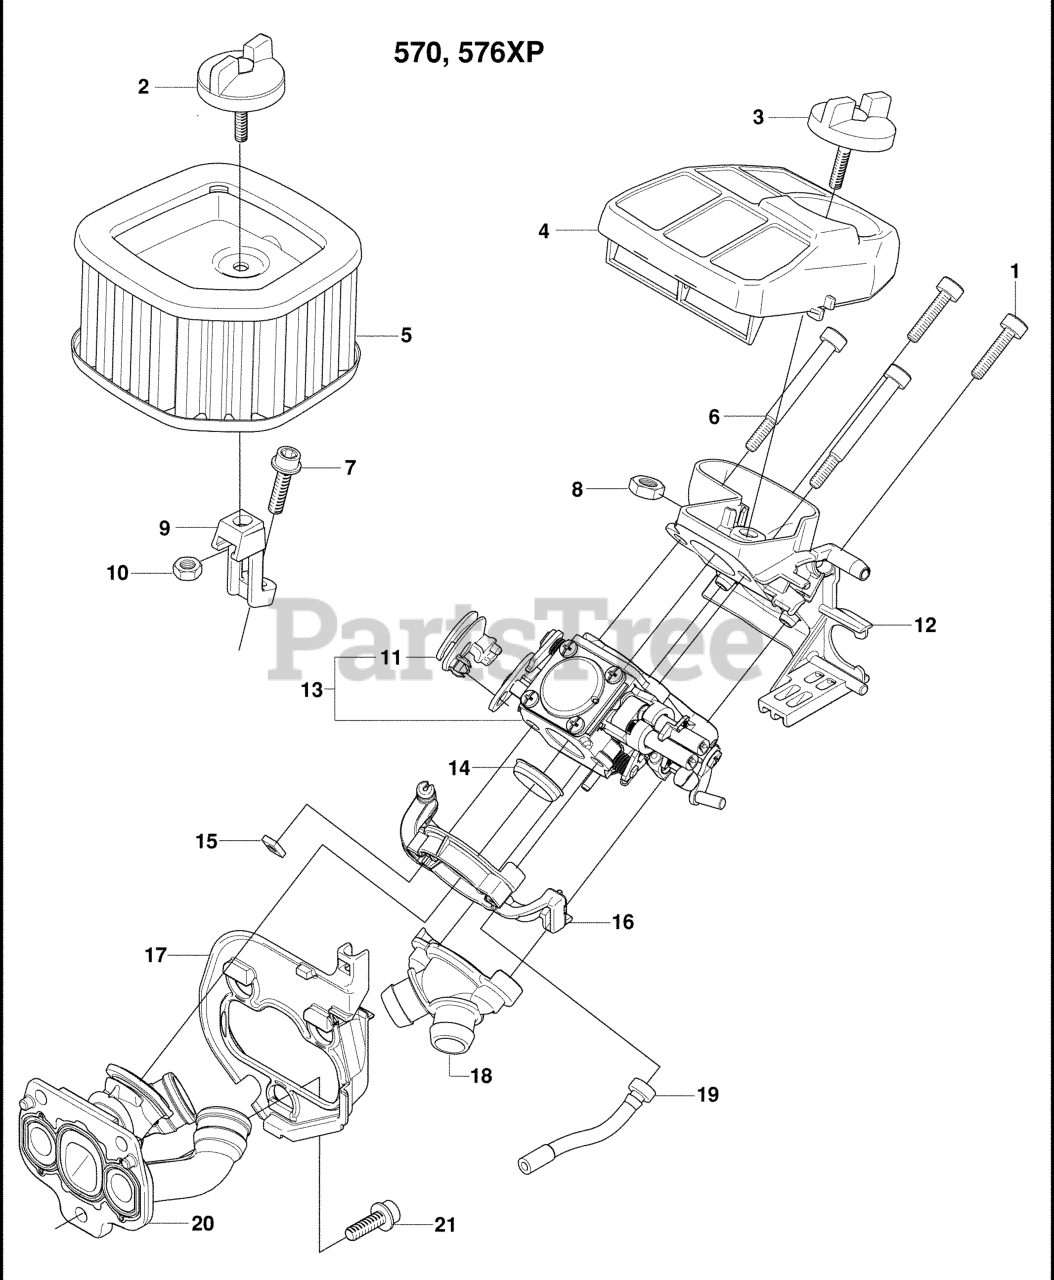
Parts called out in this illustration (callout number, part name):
4	RP AIR FILTER
4	%AIR FILTER
5	AIR FILTER
5	AIR FILTER WINTER
5	AIR FILTER HD 44
6	SCREW 4X46
12	FILTER HOLDER
13	RP CARBURETOR
